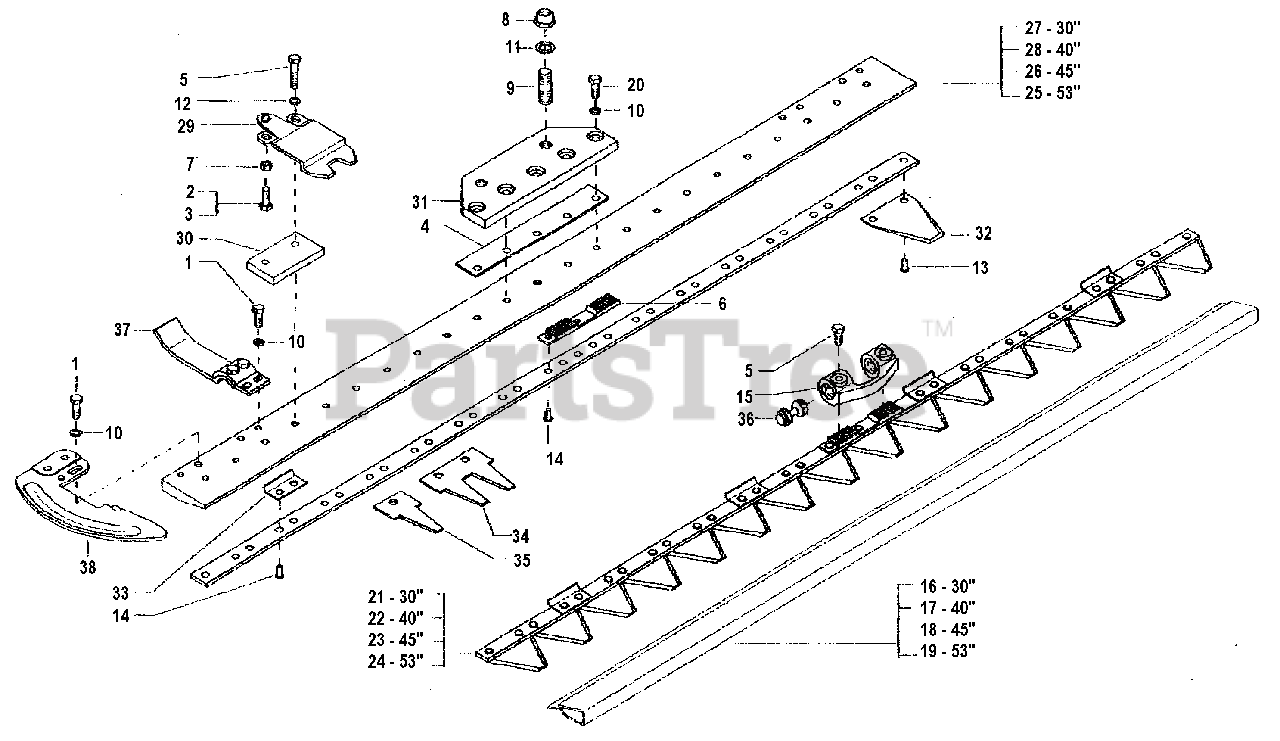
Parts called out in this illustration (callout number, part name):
1	SCREW, M8X16
2	SCREW, M8X20
3	SCREW, M8X25
4	SPACER PLATE
5	SCREW, M8X35
6	MOUNTING PLATE
8	SPECIAL NUT, M14
9	STUD, M14X1.5X44
10	SUPER WASHER, M8
11	SUPER WASHER, M14
12	WASHER, LOCK, M8
13	RIVET M6.5X13
14	RIVET M6.5X16
15	BLADE COUPLER
16	BLADE GUARD 30"
17	BLADE GUARD 40"
18	BLADE GUARD 45"
19	BLADE GUARD 53"
21	BLADE ASSEMBLY, SERAT
22	BLADE ASSEMBLY, SERAT
23	BLADE ASSEMBLY, SERAT
24	BLADE ASSEMBLY, SERAT
25	SLIDE FOR CUTTER BAR
26	SLIDE FOR CUTTER BAR
27	SLIDE FOR CUTTER BAR
28	SLIDE FOR CUTTER BAR
29	BLADE HOLDER
30	BLADE GUIDE BLOCK
31	BAR COUPLING
32	INDIVIDUAL BLADE, SERATED
34	DOUBLE FINGER
35	SINGLE FINGER
36	SCREW, BLADE COUPLING
37	SKID WITH SCREW
38	END GUARD, PAIR
